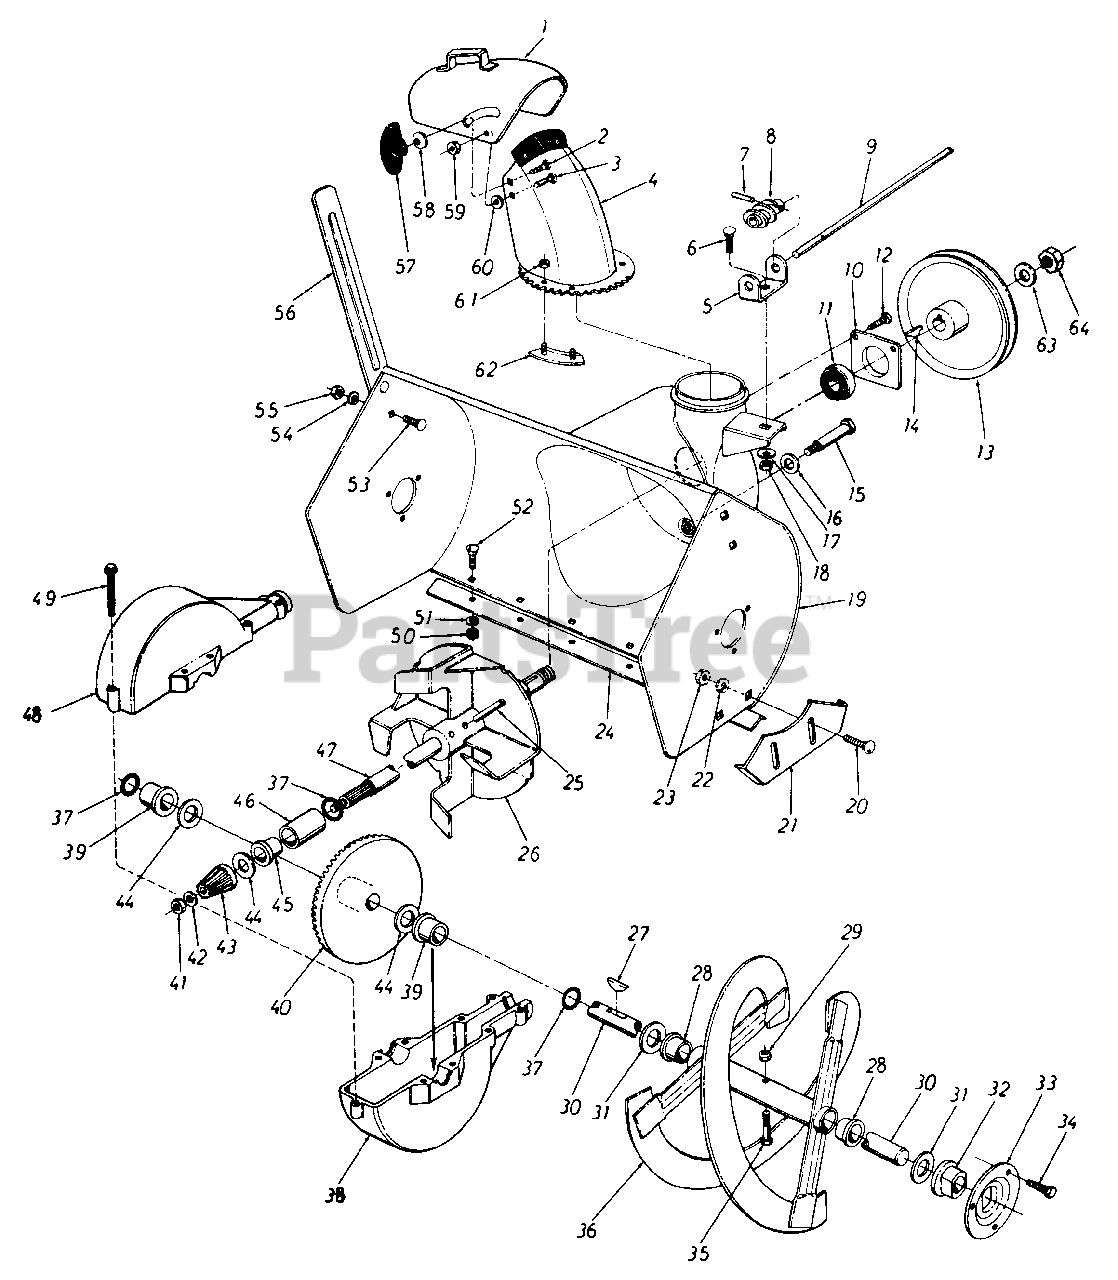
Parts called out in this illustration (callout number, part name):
1	Top Chute Ass'y.
2	Carriage Bolt 5/16-18 x 1.00" Lg.
3	Carriage Bolt 5/16-18 x .62" Lg.
4	Chute Ass'y.
5	Chute Brkt.
6	Carriage Bolt 5/16-18 x .62" Lg.
7	Spring Pin Roll 1/8" Dia. x .75" Lg.
9	Chute Crank Rod .38" Dia. x 41.0" Lg.
10	Bearing Plate
11	Spherical Brg. .75" I.D.
12	Hex Wash. Hd. Self-Tap. Scr. 5/16-24 x .50" Lg.
13	1/2" "V"-Pulley .625" I.D. x 7.50" O.D.
14	#61 Hi-Pro Key 3/16" x 5/8" Dia.
15	Shld. Bolt .498" Dia. x 2.47" Lg.
16	Bell-Wash. .40" I.D. x .88" O.D. x .06
17	Bell-Wash. .34" I.D. x .88" O.D. x .06
18	Hex Nut 5/16-18 Thd.
19	22" Blower Housing Ass'y.
20	Carriage Bolt 3/8-16 x .62" Lg.
21	Slide Shoe
22	L-Wash. 3/8" I.D.
23	Hex Jam Nut 3/8-16 Thd.
26	11" Dia. Blower Fan Ass'y.
27	#9 Hi-Pro Key 3/16 x 3/4" Dia.
28	Flange Brg. .75" I.D. x .88" O.D. x .62
29	Hex Ins. L-Nut 5/16-18
30	Spiral Axle
31	Fl-Wash. .75" I.D. x 1.50" O.D. x .06
32	Flange Brg. w/Flats .755" I.D.
33	Bearing Housing
34	Hex Wash. Hd. Self-Tap Scr. 5/16-24 x .50" Lg.
35	Hex Bolt 5/16-18 x 1.50" Lg.
36	Spiral Ass'y. - L.H.
37	"O"-Ring - 3/4" I.D.
38	Bevel Gear Housing - Lower Half
39	Plastic Flange Brg. .755" I.D.
40	Bevel Gear
41	Hex Cent. L-Nut 5/16-18 Thd.
42	Fl-Wash..34" I.D. x .62" O.D. x .06
43	Pinion Gear
44	Fl-Wash. .75" I.D. x 1.25" O.D. x .06
45	Flange Brg. .755" I.D.
46	Sleeve Brg. .755" I.D.
47	Blower Axle
48	Bevel Gear Housing - Upper Half
49	Hex Wash. Hd. Self-tap Scr. 1/4-20 x 1.00" Lg.
50	Hex Nut 5/16-18 Thd.
51	L-Wash. 5/16" I.D.
52	Carriage Bolt 5/16-18 x .62" Lg.
53	Carriage Bolt 5/16-18 x .62" Lg.
54	L-Wash. 5/16" I.D.
55	Hex Nut 5/16-18 Thd.
56	Drift Cutter Bar
57	Knob
58	Bell-Wash. .34" I.D. x .88" O.D.
59	Hex Cent. L-Nut 5/16-18 Thd.
60	Fl-Wash. .53" I.D. x 1.25" O.D. x .100
61	Hex Cent. L-Nut 1/4-20 Thd.
62	Chute Flange Keeper Ass'y.
63	Fl-Wash. .64" I.D. x .94" O.D. x .06
64	Hex Jam Nut 5/8-18 Thd.
